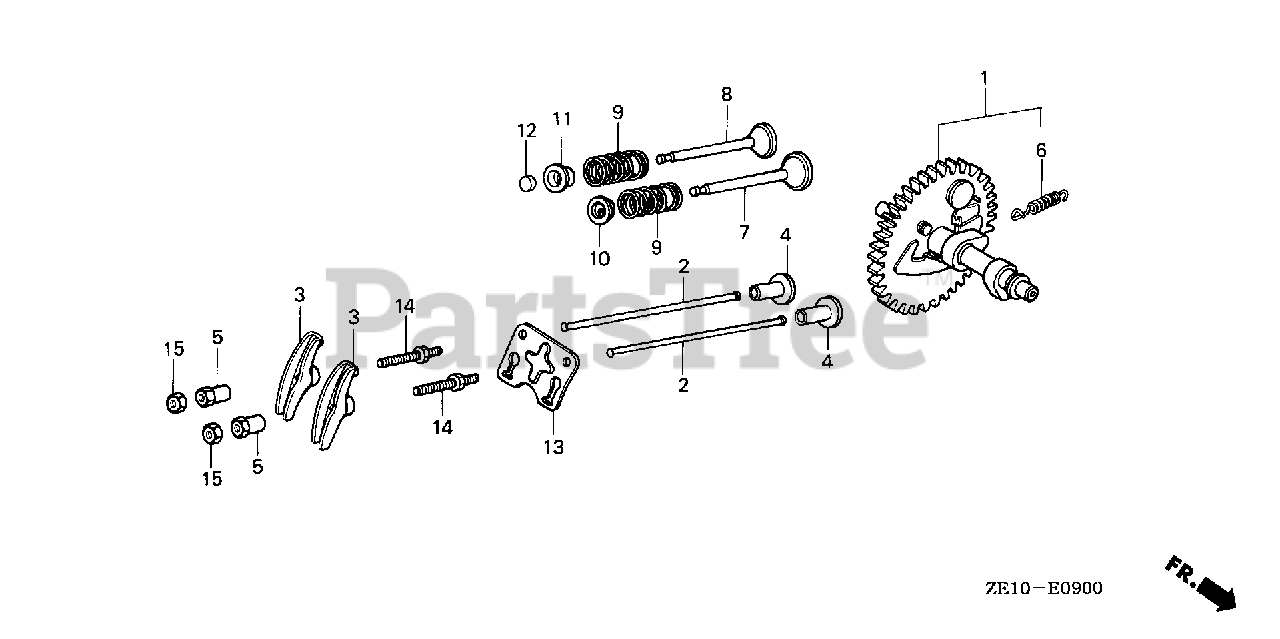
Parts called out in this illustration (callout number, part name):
1	CAMSHAFT ASSY.
2	ROD, PUSH
3	ARM, VALVE ROCKER
4	LIFTER, VALVE
5	PIVOT, ROCKER ARM
6	SPRING, WEIGHT RETURN
7	VALVE, IN.
8	VALVE, EX.
8	VALVE, EX. (STELLITE)
9	SPRING, VALVE
10	RETAINER, IN. VALVE SPRING
11	RETAINER, EX. VALVE SPRING
12	ROTATOR, VALVE
13	PLATE, PUSH ROD GUIDE
14	BOLT, PIVOT (6MM)
14	BOLT, PIVOT (8MM)
15	NUT, PIVOT ADJUSTING
